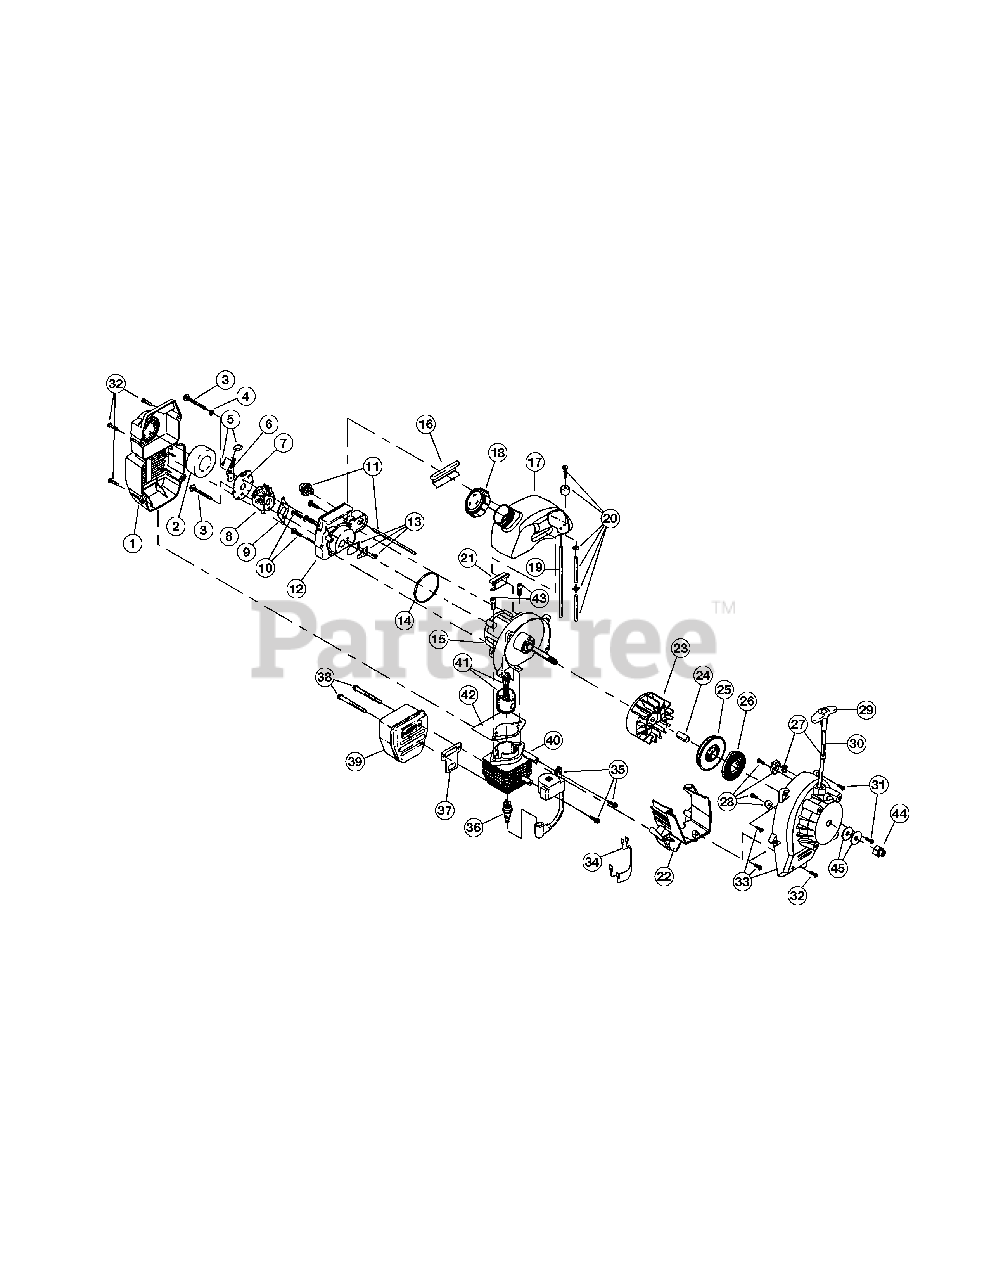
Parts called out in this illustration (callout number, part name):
1	Air Cleaner/Muffler Cover Assembly
2	Air Cleaner Filter
3	Carburetor Mounting Screw
4	Wavey Washer
5	Choke Knob and Screw
6	Choke Lever Assembly
7	Choke Lever and Plate
8	Carburetor Assembly
9	Carburetor Gasket
10	Carb Mount Screw
11	Primer and Hose Assembly
12	Carb Mount Assembly
13	Reed Assembly
15	Crank Case Service Assembly
16	Rear Mounting Pad
17	Fuel Tank Assembly
18	Fuel Cap Assembly
19	Fuel Return Line
20	Fuel Line Assembly
21	Front Mounting Pad
22	Shroud Extension
23	Flywheel Assembly
24	Spacer
25	Recoil Pulley Assembly
26	Recoil Spring
27	Rope Guide
28	Pulley Retainer Assembly
29	Pull Handle
31	Housing Screw
32	Cover Screw
33	Starter Housing Assembly
34	Wire Lead Assembly
35	Module Assembly
36	Spark Plug
37	Exhaust Gasket
38	Muffler Mounting Bolt Assembly
39	Muffler Assembly
40	Cylinder Assembly
41	Piston and Rod Assembly
42	Cylinder Gasket
43	Cylinder Bolt
44	Impeller Drive Nut
45	Washer
